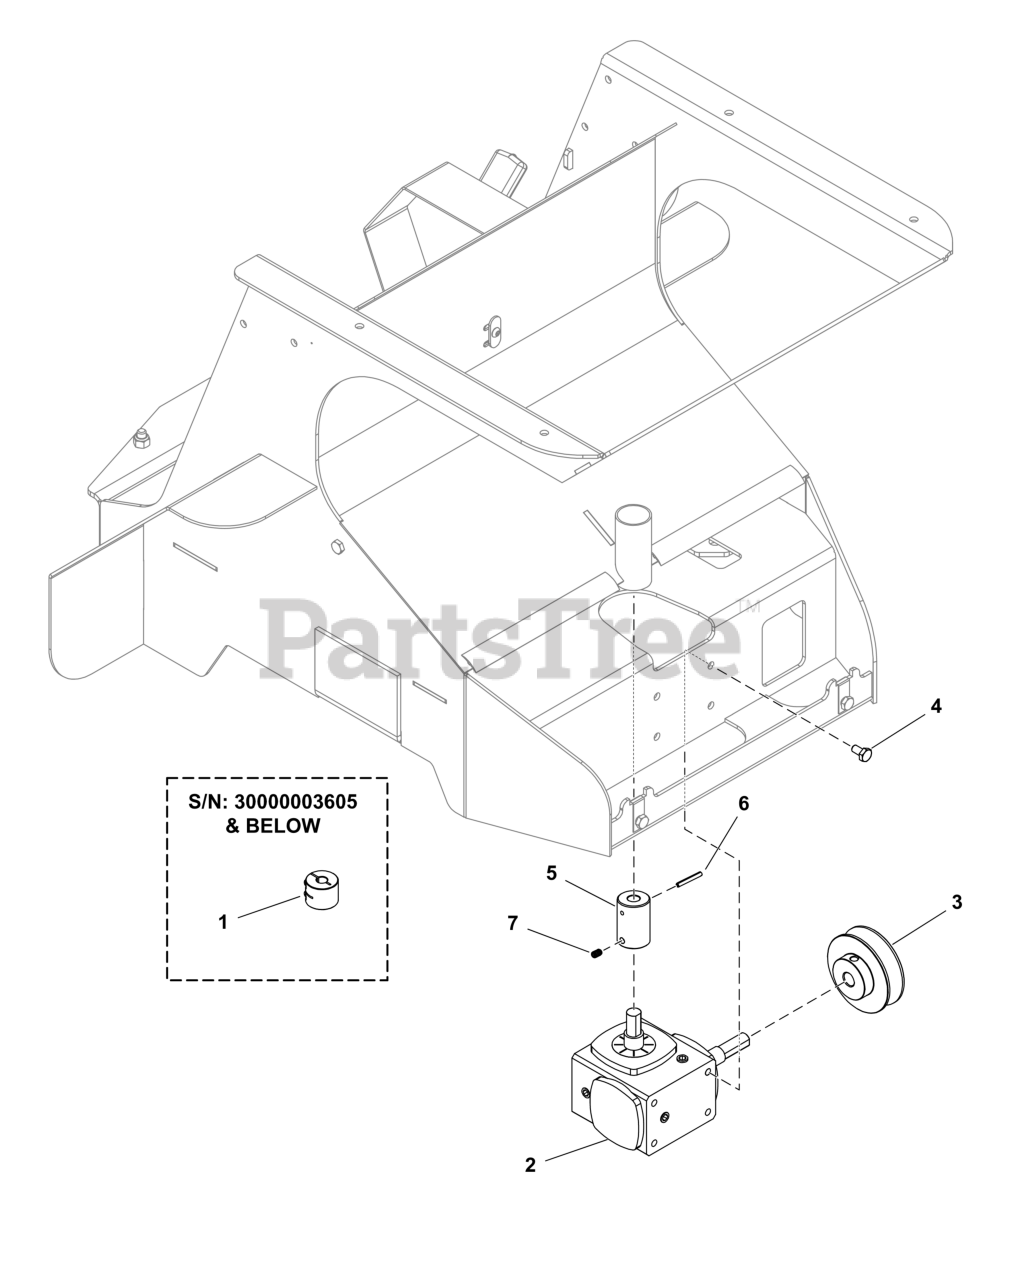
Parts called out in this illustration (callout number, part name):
1	KIT, PLATTER SHAFT COUPLING
2	GEAR REDUCER W/ Ø.375" SHAFT
2	GEAR REDUCER W/ Ø.500" SHAFT
2	GEAR REDUCER W/ 2.50" LONG Ø.500" SHAFT
3	PULLEY, 2.95" O.D. x 0.500" I.D. V, A/B
4	SCR-CAP, HEX .250"-20 X .500" SS188
5	COUPLING, SS, PLATTER SHAFT
6	PIN, COILED SPG, SS, .125" DIA X 1.00"LG
7	SCREW, SET, .190" DIA X .3125" LG. 18-8
